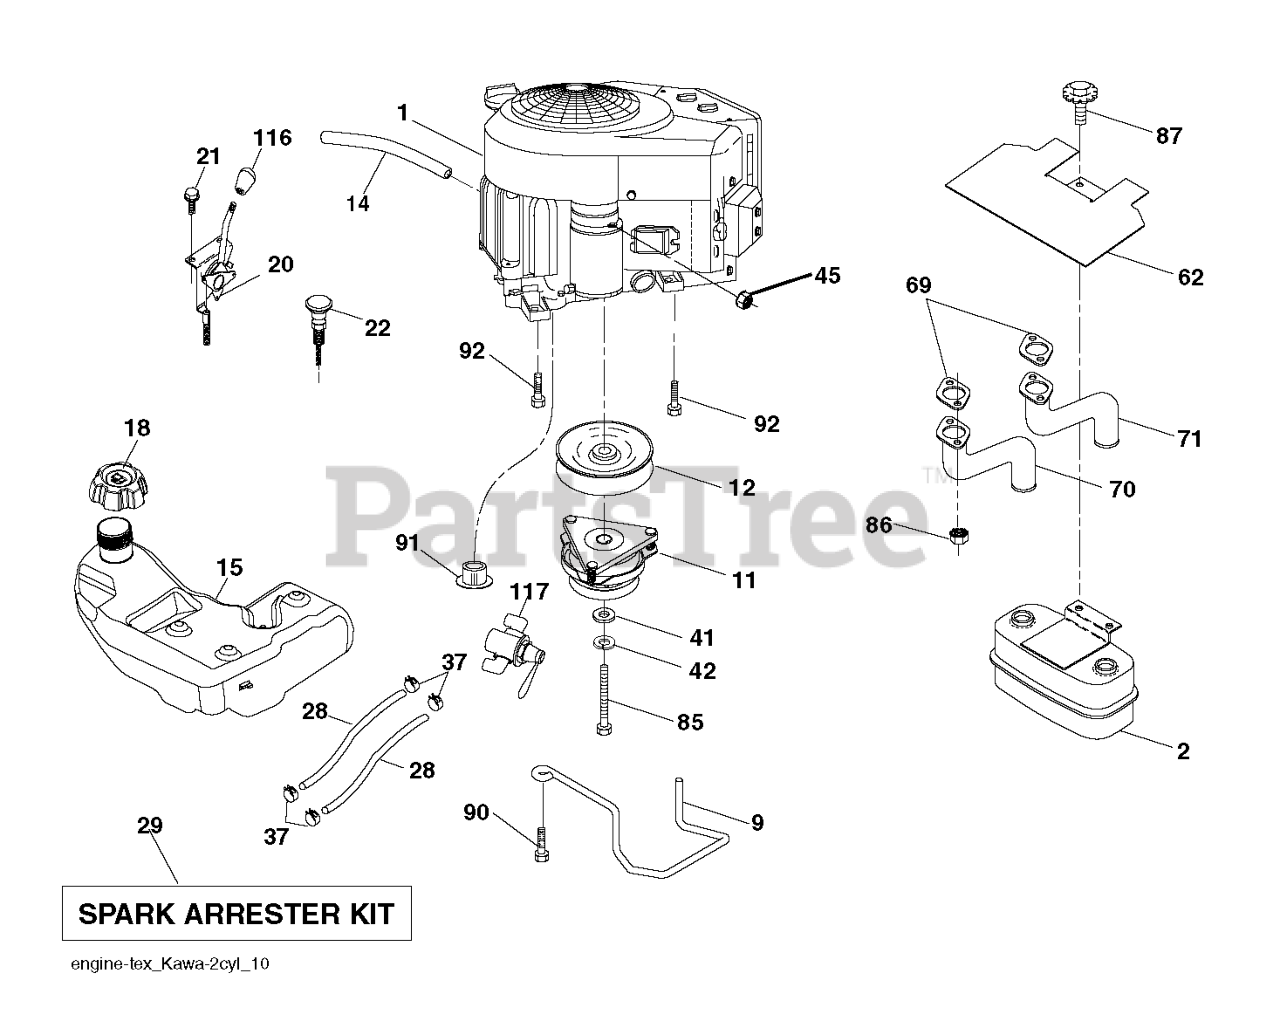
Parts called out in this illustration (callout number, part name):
2	MUFFLER.ASM.TWN.EXTNDED.DFLCTR
9	KEEPER BELT ENGINE
11	CLUTCH MZ ZTR GT.48/54"1.125"
12	PULLEY ENGINE
14	TUBE, DRAIN OIL ASM.
18	CAP.FL.R.3'N/CARB.H.CROWN.498
20	CONTROL.THROTTLE.PRO.
21	SCREW.#10 X 0.750.BOS
22	CONTROL.CHOKE.ERGO.PUSH-IN.BLA
28	LINE.FUEL.64"REAR.EMIS
29	KIT.SPARK ARRESTOR 794945 B&S
37	HOSE CLAMP
42	LOCKWASHER
45	NUT
62	SHIELD.HEAT.MUFFLER
70	TUBE.EXHAUST.LH.FR961/FR730
71	TUBE.EXHAUST.RH.FR961/FR730
85	BOLT HEX 7/16-20 X 3.75 GR. 5
86	BOLT.5/16-18UNCX3/4 W/SEMS.BLK
87	BOLT.5/16-18UNCX1.W/SEMS.BLK
90	SCREW 3/8-16X1
91	BUSHING.1.375OD
92	SCREW 3/8-16X1
116	KNOB - SHIFT
117	VALVE FUEL RESERVE
